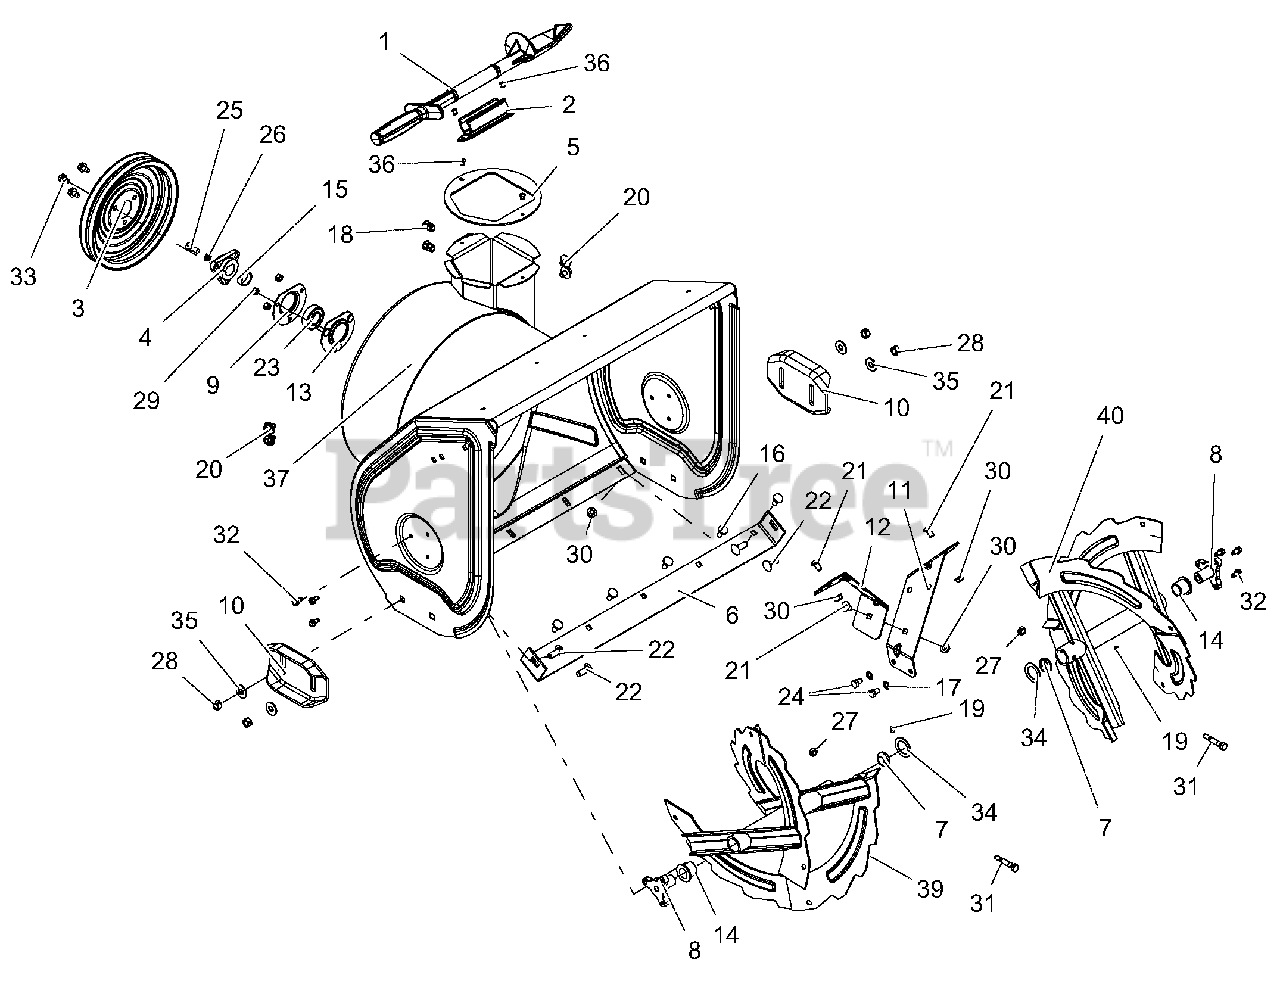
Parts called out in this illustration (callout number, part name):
1	DEVICE, SNOW CLEAN OUT
2	MOUNT, SNOW CLEAN OUT
3	PULLEY, SPIN FORM DUAL GROOVE
4	PULLEY HUB, D-BORE .87 DELUXE
5	BAFFLE, DISCHARGE NECK
6	BLADE, SCRAPER-24"
7	PLUG, RAKE TUBE
8	SUPPORT, RAKE BUSHING
9	BEARING FLANGE
10	SKID SHOE, REVERSIBLE - ORANGE
11	BRACKET, GEARCASE SUPPORT - LH
12	BRACKET, GEARCASE SUPPORT - RH
13	BEARING FLANGE
14	BSHG-FLG, NY.778 ID X 1.018 OD
15	BSHG-SPCR .895IDX1.065ODX.353
16	BOLT, MODIFIED HEAD CARRIAGE
17	@WSHR-LK-EXT.326X.599X.031YWZC
18	NUT, THREADED INSERT .38-16
19	ZERK,FITTING .25X.125 DRIVE IN
20	SCR-TAP.31-18X.50 HWH TR YWZ
21	BLT-RDHDSQSHNK.31-18X.62 YZ-LK
22	@BLT-RDHDSHSQNK.38-16X1.0 G5YZ
23	BRG-BALL .876 X 1.750 X .50
24	@BLT-HEX .31-18X.50 GR5 YWZC
25	BLT-HEX .31-24X.75 YWZC GR5
26	WSHR-LK .312X.097 HVY YWZC
27	@NUT-LK-CTR .31-18 YWZC
28	@NUT-LK-CTR .38-16 YWZC
29	@NUT-LK-CTR .25-20 YWZC
30	@NUT-LK-TOP-FLG .31-18 YWZC
31	SHEAR BOLT SERVICE ASSEMBLY
32	SCR-TAP .25-20X.50 HWH TR YWZ
33	@SCR-TAP .31-18X.50 HWH TR YWZ
34	WSHR-FL-STL 1.010X1.505X.062YZ
35	@WSHR-FL-STL.438X1.00X.083 YWZ
36	RVT-POP .187 YZ
37	BLOWER HOUSING W/DECAL 24"
39	RAKE, RH W/ZERK - 24"
40	RAKE, LH W/ZERK - 24"
